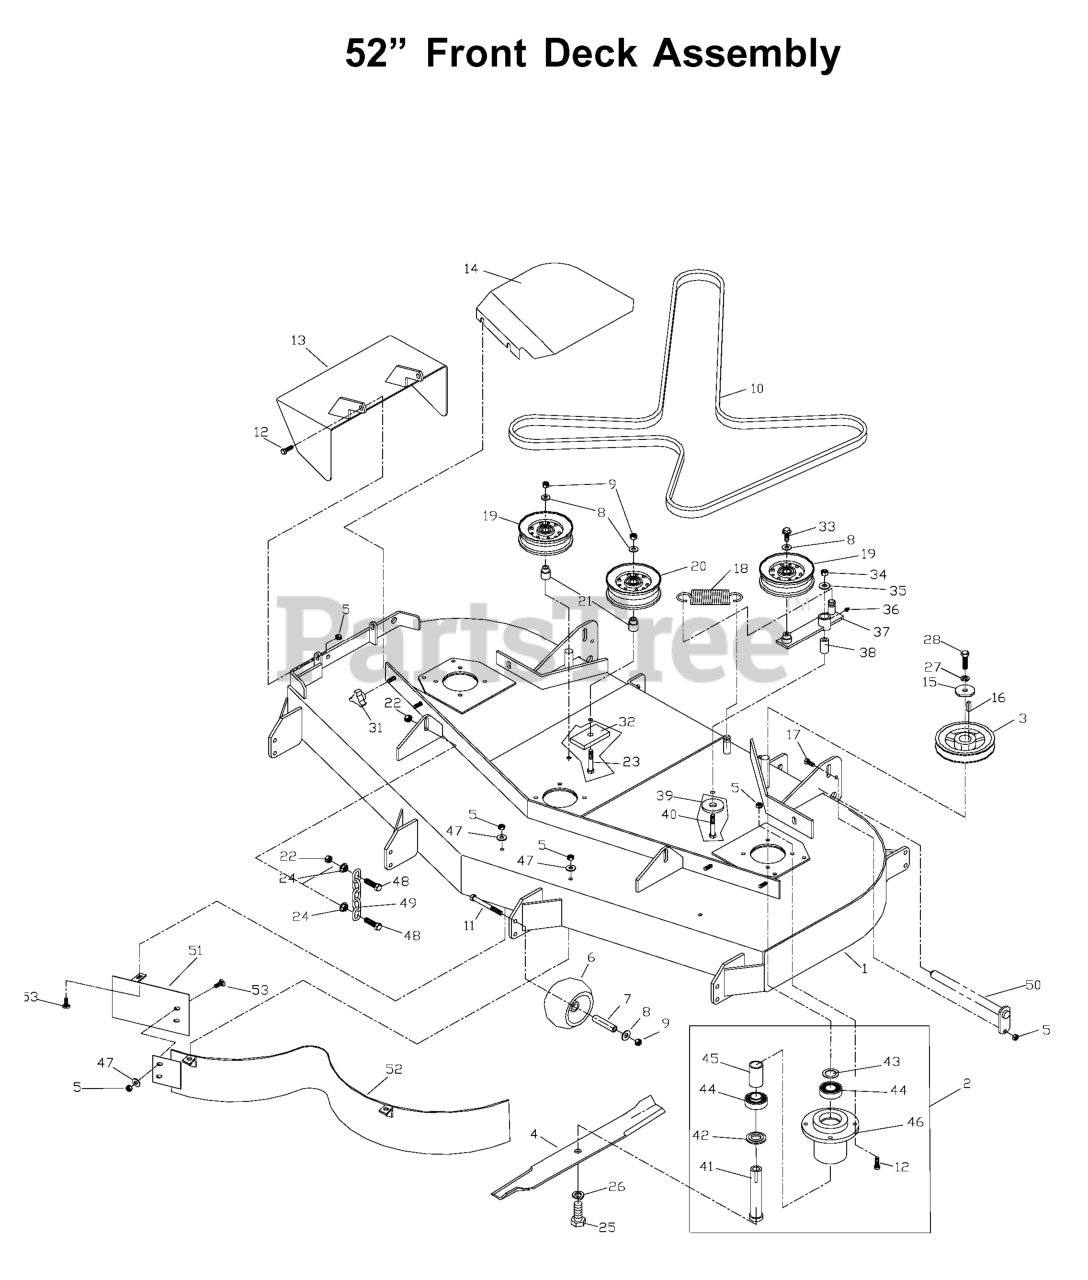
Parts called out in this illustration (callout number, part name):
1	DECK W/DECALS 52" HUS WSL
2	HOUSING ASM.
3	PULLEY 52" DECK
4	BLADE OEM 18"
5	NUT 5/16C CENTERLOCK
6	ANTI-SCALP ROLLER
8	WASHER 3/8 FLAT
9	NUT 3/8C CENTERBLOCK
10	BELT, DECK
11	HCS 3/8C X 3 1/2
12	HCS 5/16C X 1
13	DISCHARGE CHUTE ORANGE
14	52 B.S.PAINTED,RT
15	SPINDLE WASHER
16	KEY 1/4 SQ X 1 1/8
17	HCS 5/16C X 3/4
18	DECK SPRING
19	IDLER PULLEY
20	IDLER PULLEY (TALL)
21	IDLER BUSHING
22	NUT 7/16C CENTERLOCK
23	HCS 3/8C X 2 1/2
24	NUT 7/16C WHIZ
25	HCS 5/8F X 1 1/4
26	LOCKWASHER 5/8
27	WASHER 7/16 LOCK
28	HCS 7/16F X 1 1/2
31	KNOB, THREE PRONG
32	SUPPORT PLATE
33	4CS 3/8C X 1 SERRATED HEAD
34	NUT 1/2-13 HEX NYLOC ZD
35	WASHER 1/2 FLAT
36	ZERK
38	PIVOT BUSHING
39	WASHER, SUPPORT
40	HCS 1/2C X 3 1/4
42	MACHINERY BUSHING 10 GA.
43	BUSHING.MACHINE.18.GAUGE
44	BEARING
46	HOUSING, DIE CAST
47	WASHER 5/16 FLAT
48	HCS 7/16C X 1 1/2
49	LIFT CHAIN
51	CENTER BAFFLE - 52"
52	MAIN BAFFLE 52"
53	CARRIAGE BOLT 5/16C X 5/8"
539105105	52 B.S.PAINTED, LT
